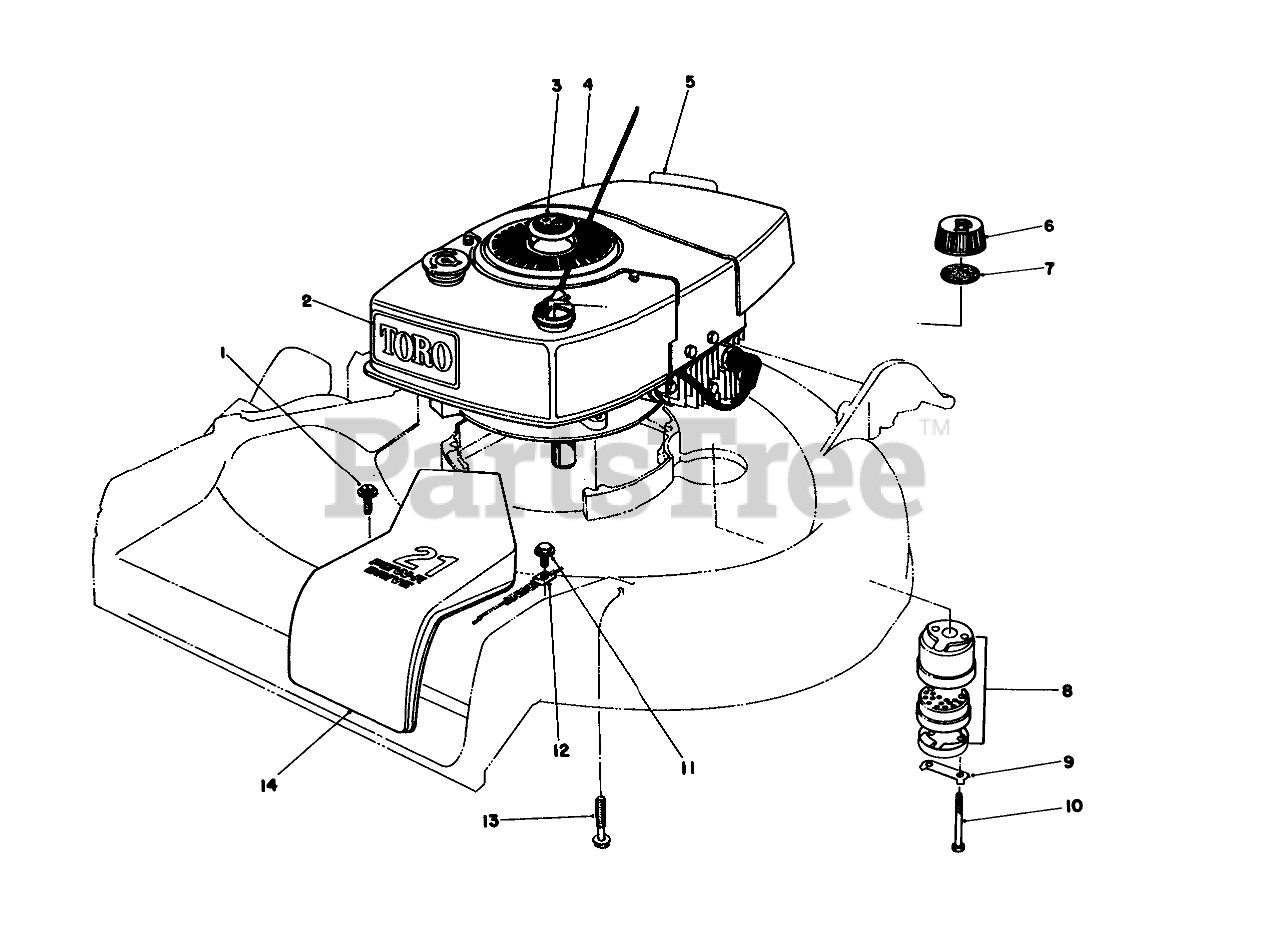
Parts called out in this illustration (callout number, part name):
1	SCREW
2	Decal Tow
3	PLUG BUTTON
4	Engine
5	Decal-Maintenan
6	Gas Cap Assembly (Incl. Ref. #7)
7	GAS CAP GASKET
8	Muffler Assembly (Incl. #9 & 10)
9	CLIP - LOCKING
10	SCREW-HH
11	SCREW-HWHTF
12	Cable Clamp
13	3/8-16 X 2-3/4 CAPSCR
14	BELT COVER 21" S D
